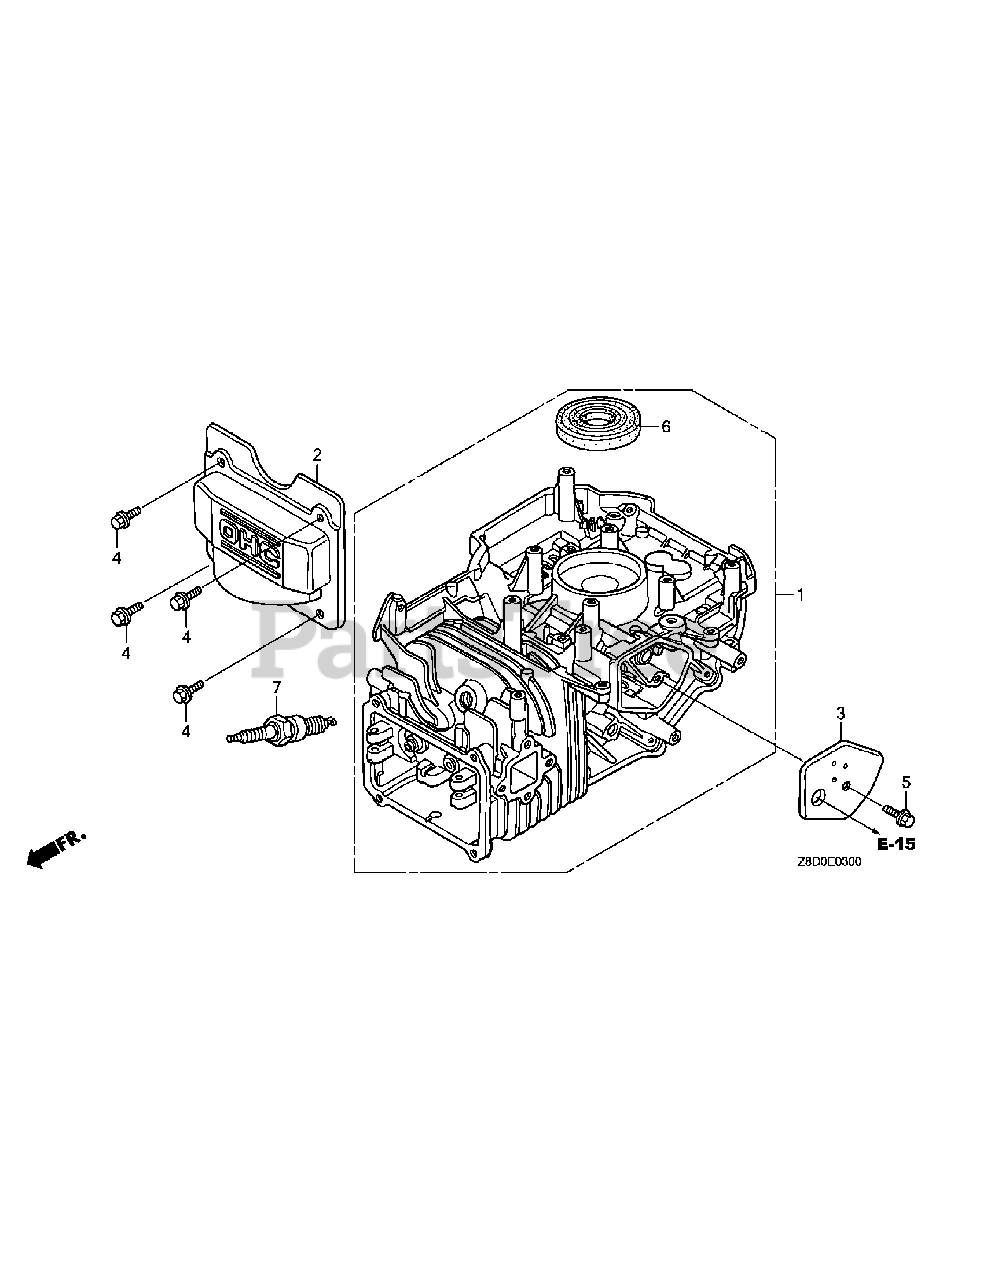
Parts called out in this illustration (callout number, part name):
1	Cylinder Barrel Assembly
2	Head Cover
3	Breather Cover Complete
4	Flange Bolt, 6 X 12
5	Flange Bolt, 6 X 14
6	Oil Seal, 25.4 X 62 X 6
7	Spark Plug (BPR6ES NGK)
